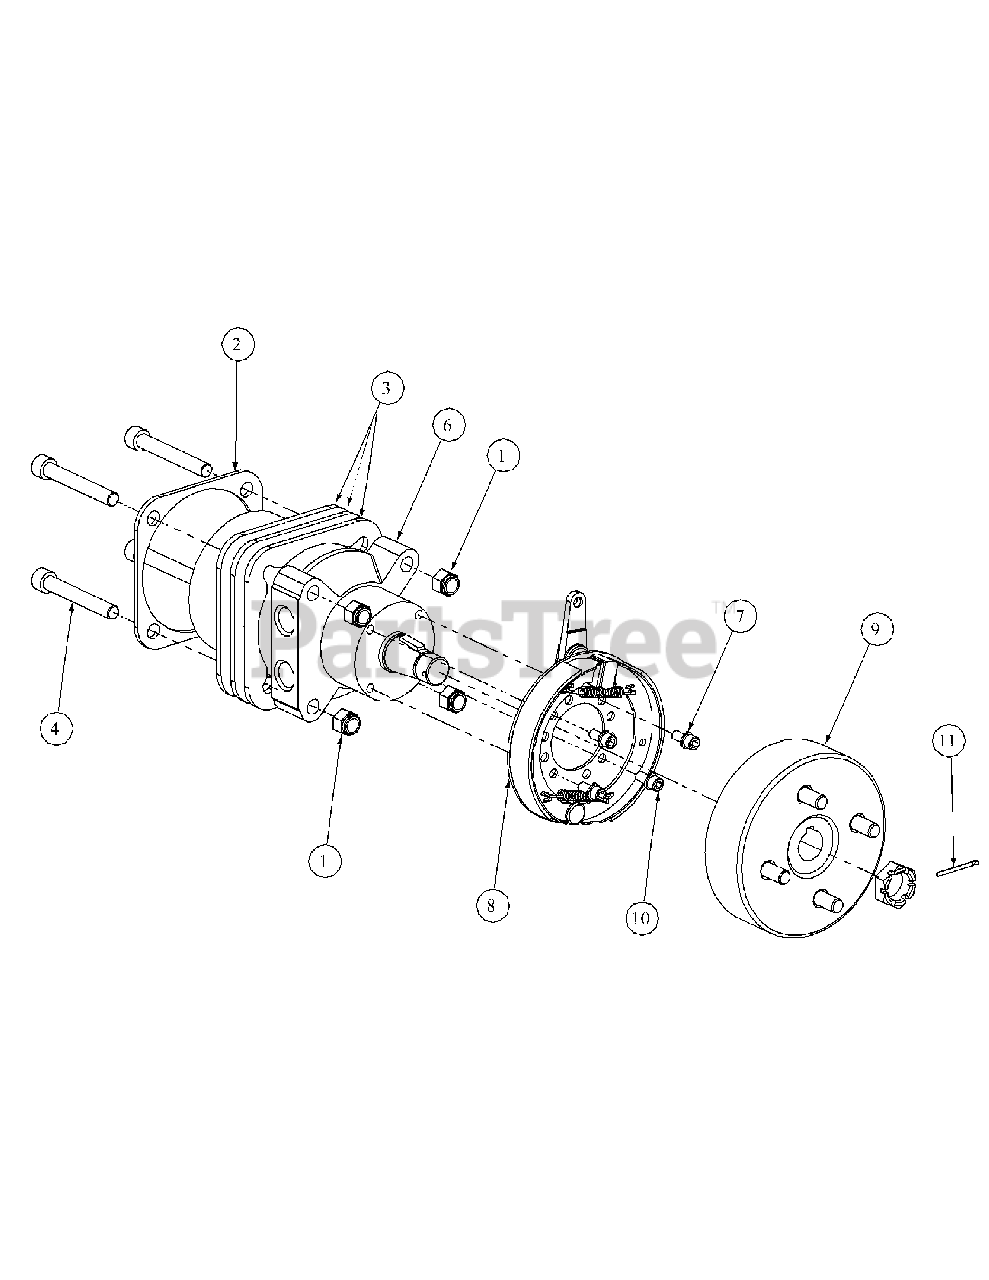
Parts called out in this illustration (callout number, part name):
1	Lock Nut, Nylon Insert, 1/2-13
2	Motor Plate
3	Motor Spacer
4	Socket Head Capscrew, 1/2-13; 3-1/2
4	Capscrew, 1/2-13 x 3.5
5	Hyd. Motor, Parker Left Hand
6	Hydro Motor, Parker Right Hand
7	Lock Washer, 5/16
8	Brake Assembly w/Line
9	Hub and Drum Assembly w/Studs
10	Capscrew w/Socket, 5/16-18 x 3/4
11	Cotter Pin 1/8 x 1-1/2
